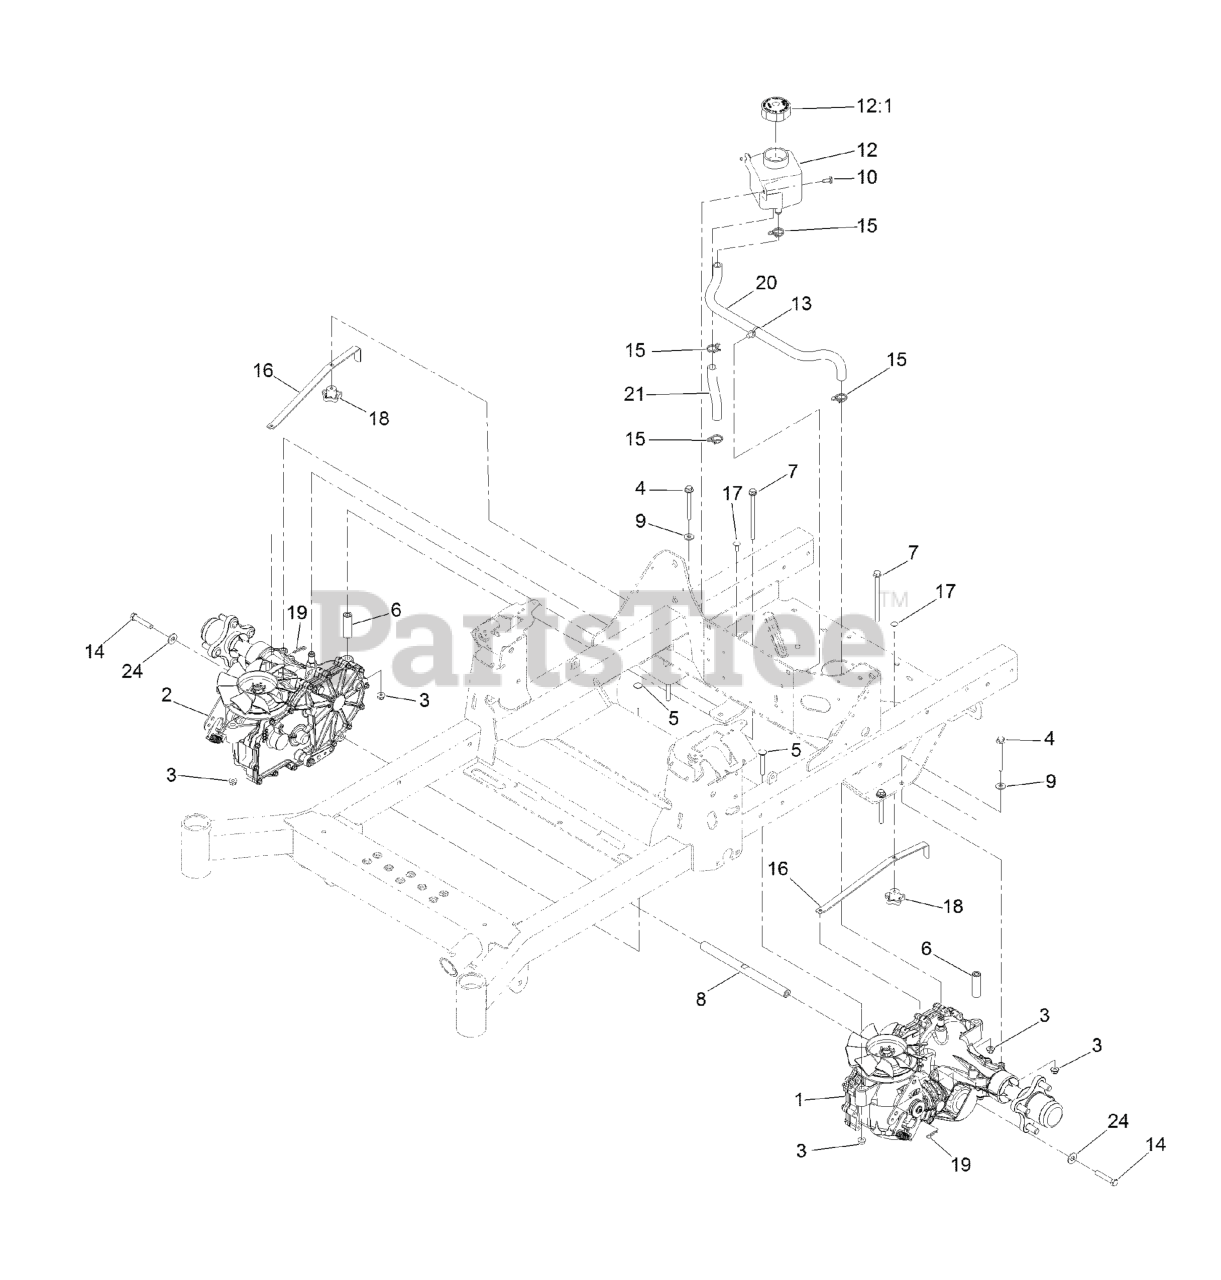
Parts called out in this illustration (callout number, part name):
1	LH TRANSAXLE ASM
2	RH TRANSAXLE ASM
3	NUT-HF, NI
4	SCREW-HHF
5	BOLT-CARR
6	SPACER-HYDRO
7	SCREW HHF
8	SHAFT-SPACER
9	WASHER-SPRING
10	SCREW-TORX
12	TANK-HYD
12:1	CAP-RESERVOIR, HYD
13	CLIP-TIE
14	SCREW-HH W/LOCTITE
15	CLAMP-HOSE
16	ARM-BYPASS, HYDRO
17	BOLT-CARR
18	KNOB-HANDLE
19	PIN-COTTER
20	HOSE-HYDRAULIC
21	HOSE-HYDRAULIC
24	WASHER-FLAT
